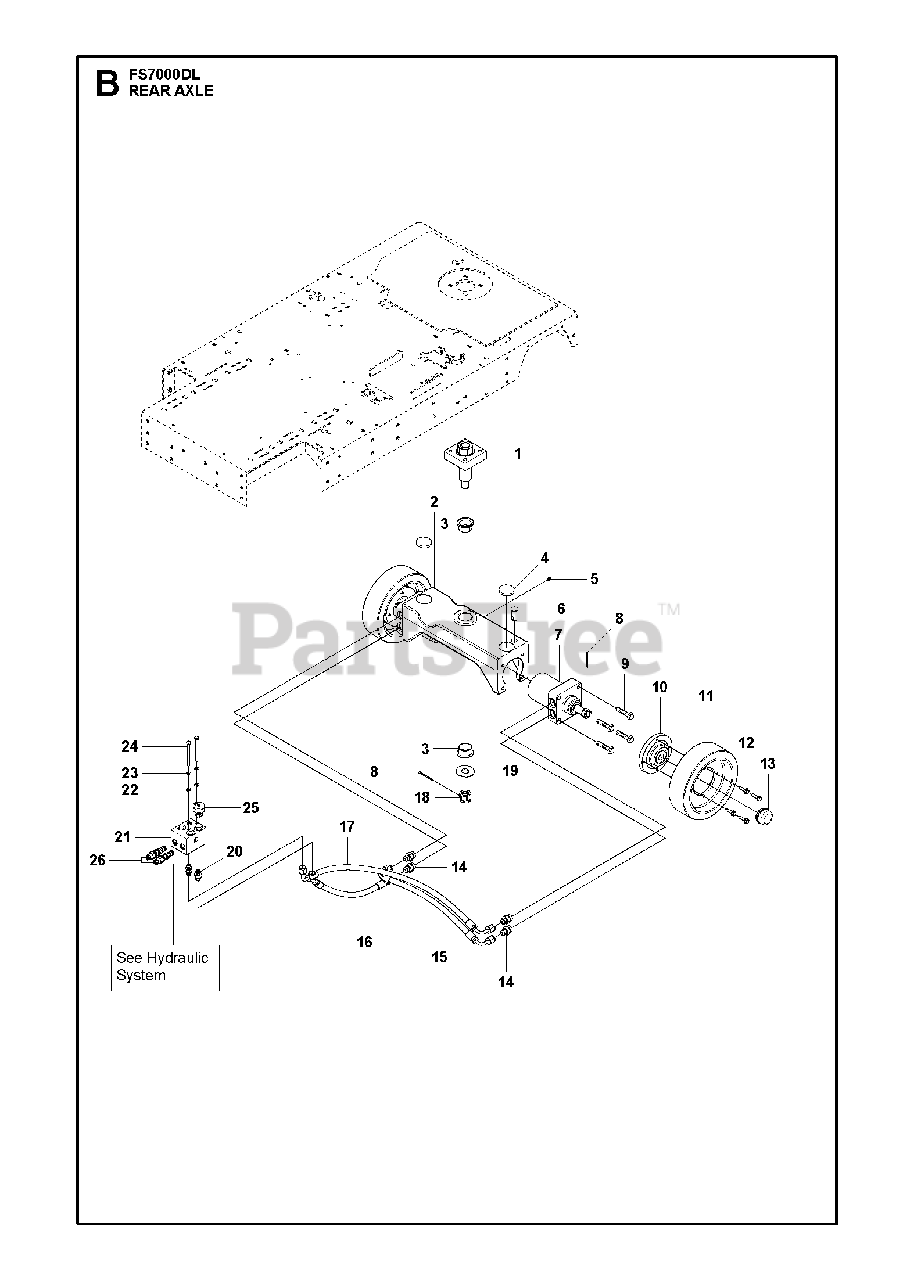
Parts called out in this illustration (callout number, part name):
2	REAR AXLERear axle + Bushings
13	CAP
22	WASHER
23	SPRING WASHER
